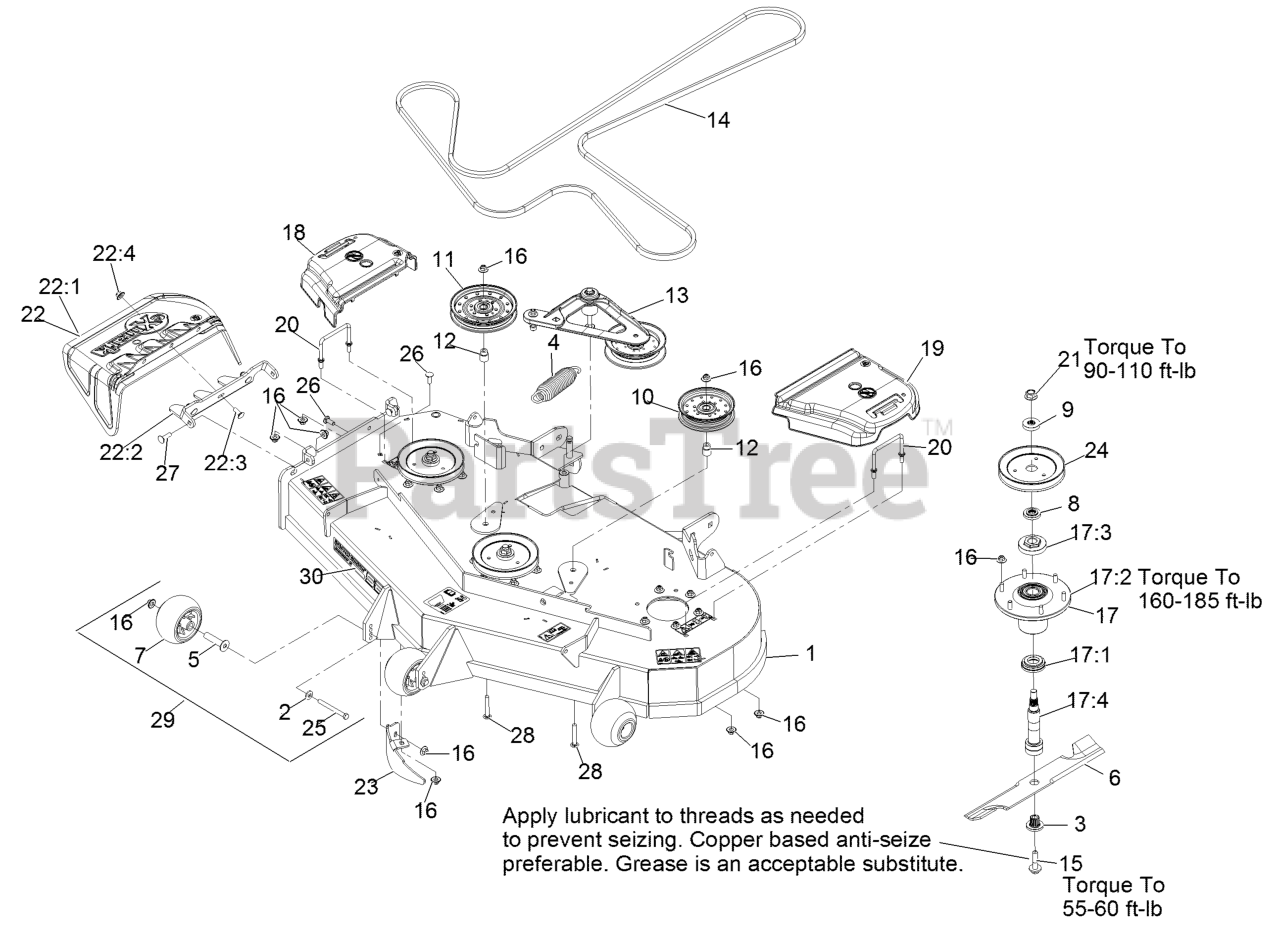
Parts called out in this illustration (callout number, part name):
1	ASM,DECK W/ DECALS 52
2	WASHER-BELLEVILLE
3	BUSHING,SPLINED
4	SPRING-EXTENSION
5	AXLE, ROLLER
7	ROLLER-SCALP, ANTI
8	SPACER,SPLINED STEPPED
9	SPACER,SPLINED
12	BUSHING-IDLER
13	DECK IDLER ASM
14	BELT,V-B X 186.00"
15	SCREW,SEMS 1/2-20 X 2.19
16	Nut-Nyloc 3/8-16 Flg
17	ASM,SPINDLE HOUSING
17:1	GUARD,BOTTOM
17:2	ASM,CUTTER HOUSING
17:3	NUT, SPINDLE 7/8-14
17:4	SPINDLE,DOUBLE SPLINE
18	COVER-BELT, RH
19	COVER-BELT, LH
20	WIREFORM-COVER
21	NUT-FLANGE, CENTERLOCK
22	ASM,DISCHARGE CHUTE
22:1	CHUTE,DISCHARGE
22:2	BRACKET,DISCHARGE CHUTE
22:3	SCREW-CARR
22:4	Nut-Nyloc 3/8-16 Flg
23	BAFFLE-DOGLEG, LZ-VT52
24	SHEAVE,BLADE DRIVE
25	SCREW-HH 3/8-16 X 3 3/4 GR 8
26	SCREW-CARR
27	Bolt-Carriage 3/8-16 X 1 1/4
28	SCREW-CARR
29	KIT, ANTI-SCALP ROLLER
30	Decal, 526
